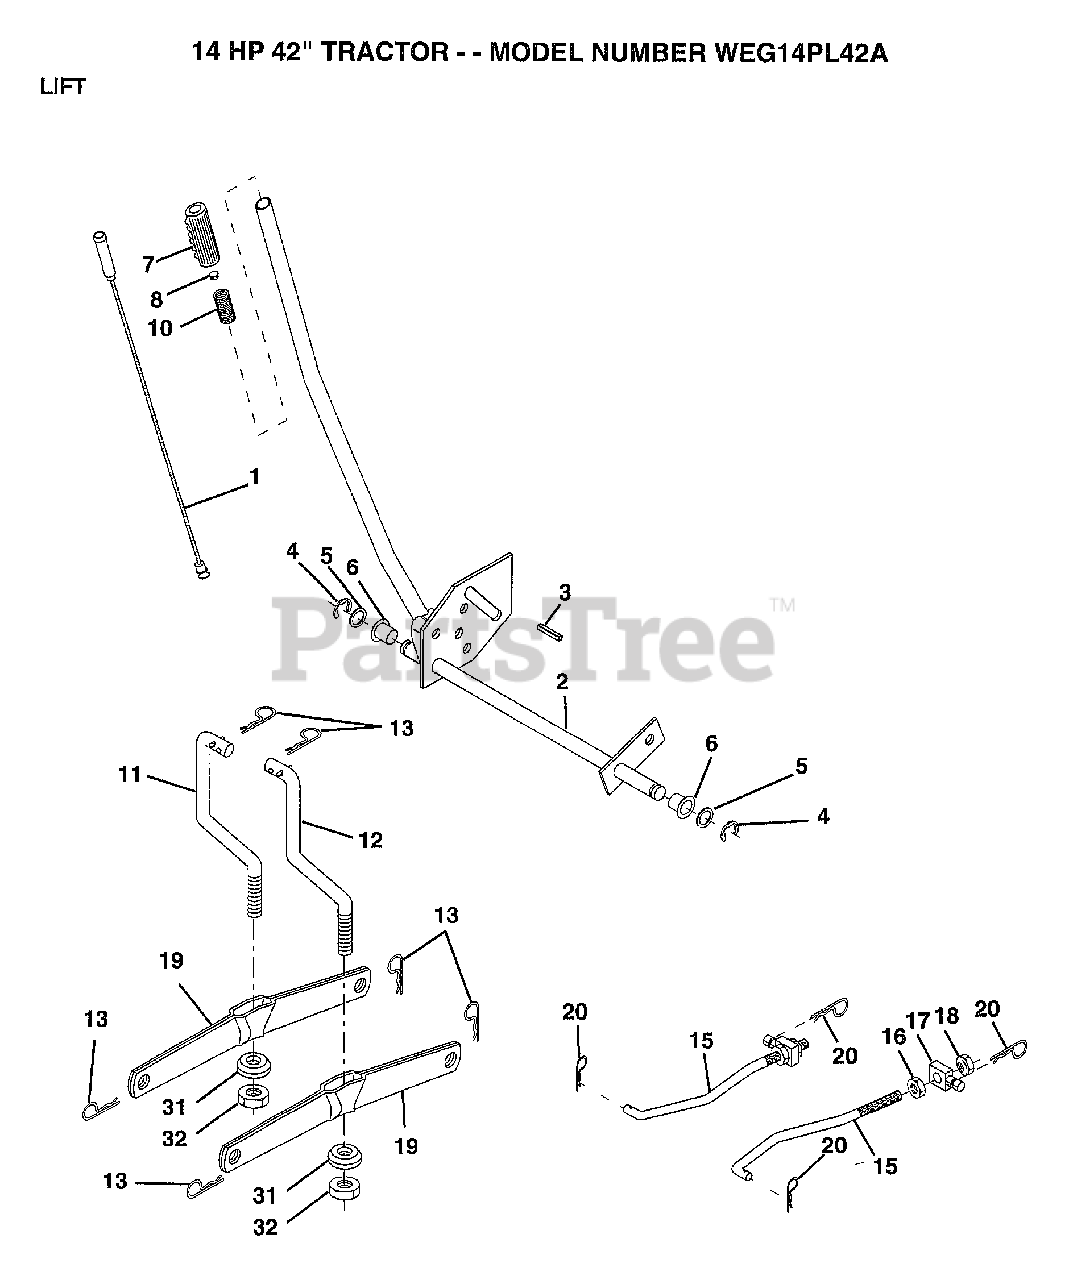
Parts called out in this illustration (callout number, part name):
1	WIRE ASM
2	HANDLE.LIFT.LH.
3	PIN GROOVE
5	WASHER
6	NYLON BEARING
7	GRIP
15	LINK.FRONT
16	NUT
17	TRUNION
18	NUT.LK.W/WSH.1/2.
19	ARM SUSP REAR
20	RETAINER.SPRING
31	BEARING PVT LH
32	NUT.LOCK.3/8-24
